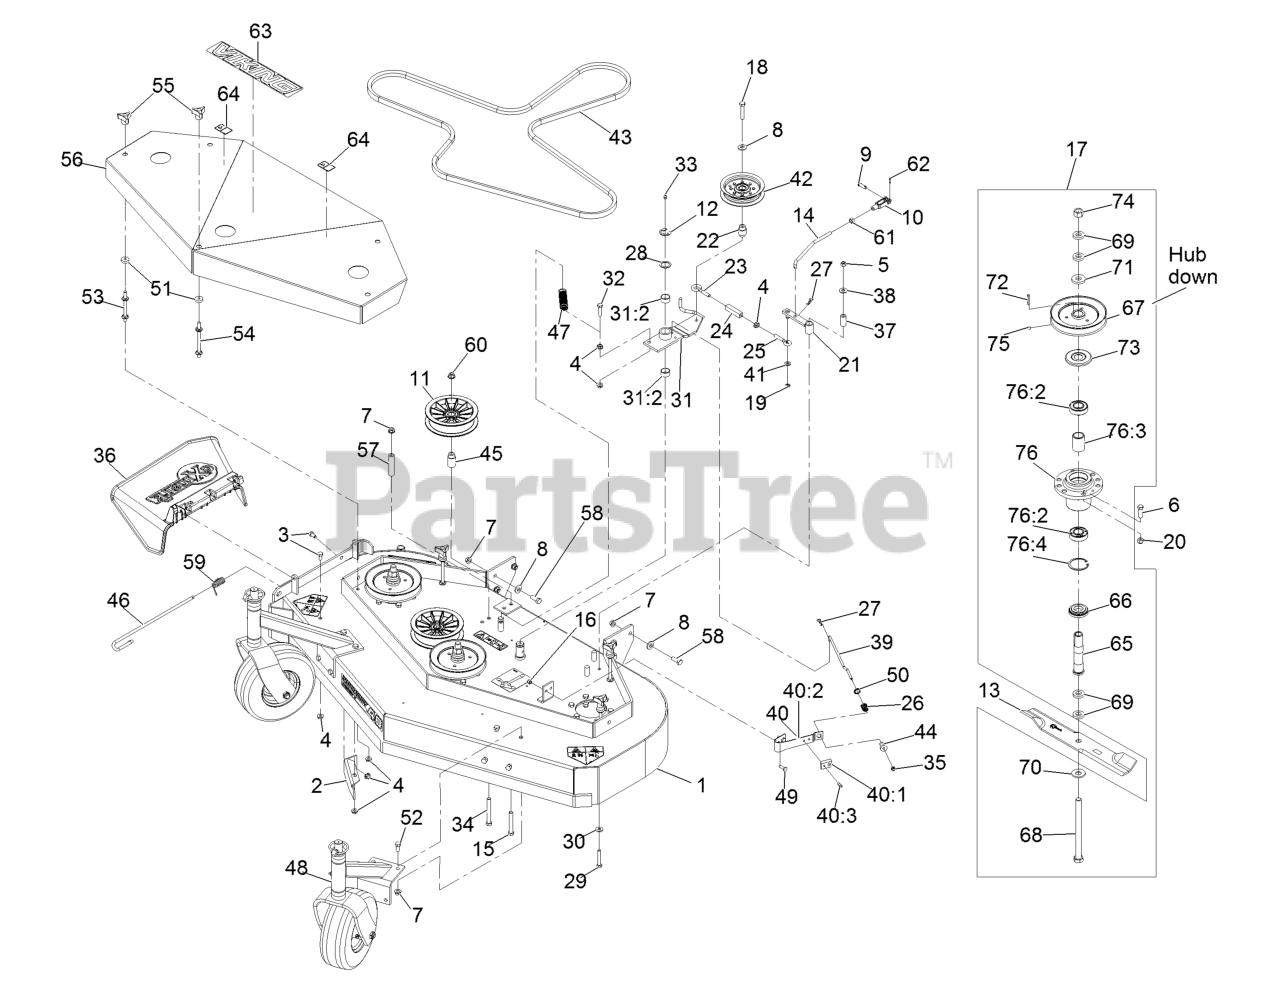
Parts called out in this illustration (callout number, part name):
1	Deck W/Decals And Dogleg
2	Baffle-Dogleg
3	Screw-HH 5/16-18 X 5/8
4	Nut-Whizlock 5/16-18
5	Nut-Nyloc 5/16-18
6	Screw-HH 3/8-16 X 1 1/4
7	Nut-Whizlock 3/8-16
8	Washer-Spring Disc 3/8
9	Pin-Clevis 5/16 X 1 49/64
10	Yoke-Adjustable
11	Pulley,Idler 5"
13	Blade, 16.25 Solid
13	Blade, 16.25 Mulching
13	Blade, 16.25 Notched
13	Blade,Low Lift 16.25
13	Blade-Extreme 2, 16.25"
14	Arm-Linkage, Assist
15	Screw-HH 3/8-16 X 2 3/4
16	Nut-Nyloc 1/4-20
17	Asm, Cutter Housing Complete
18	Screw-HH
20	Nut-Nyloc 3/8-16
21	Arm-Assist, 32/36
22	Bushing-Engagement
23	Eyebolt-Thread, LH
24	Body-Turnbuckle
25	Eyebolt-Thread, RH
26	Spring-Compression
27	Hairpin-Cotter
28	Washer-Spindle
29	Screw-HH 5/16-18 X 2
30	Washer-Spring Disc 5/16
31	Idler Arm ASM
31:2	Sleeve-Bearing
32	Screw,HH Special 5/16-18 X 1.25
33	Zerk-1/4-28 Str
34	Screw-HH 3/8-16 X 3-1/4
35	Nut-Nyloc 1/4-20 Thin
36	Deflector-Discharge
37	Tube-Pivot
38	Washer-5/16 Std
39	Rod-Brake
40	Pad And Spring ASM
40:1	Pad-Brake
40:2	Spring
40:3	Rivet 3/16 X 1/2
41	Washer-5/16 SAE
42	Pulley-Idler
43	Drive Belt (Main Deck) 48"
44	Spacer-Flanged
45	Bushing-Idler
46	Pin-Chute
47	Spring-Extension
48	ASM-Caster Mnt W/Weight
49	Screw-HH 1/4-20 X 3/4
50	Ring-Push On
51	Washer-Belt Shield
52	Screw-HH 3/8-16 X 3/4
53	Stud-Shield, Belt (Short)
54	Stud-Shield, Belt (Long)
55	Knob-3 Prong
56	Shield-Belt
56	ASM,Shield W/Decals 48 Viking
58	Screw-HH 3/8-16 X 1
59	Spring, Torsion
60	Nut-Nyloc 3/8-16 Flg
61	Nut-Hex 5/16-24
62	Pin-Cotter 3/32 X 1/2
63	Decal, Viking Hydro Model
64	Decal-Warning
65	Tube-Spindle, Short
66	Spacer-Guard Bottom
68	Screw-Cap, HH
69	Spacer-Blade Drive
70	Washer-Spring Disc 5/8
72	Key-Machine 1/4 X 3/16 X 1 1/4
73	Guard-Bearing Top
74	Nut-Hex 5/8-18
75	Setscrew-5/16-18 X 3/8
76	Cutter Housing ASM
76	Asm, Cutter Housing W/Bearings
76:2	Bearing-Jackshaft
76:3	Spacer-Bearing
76:4	Ring-Retaining
